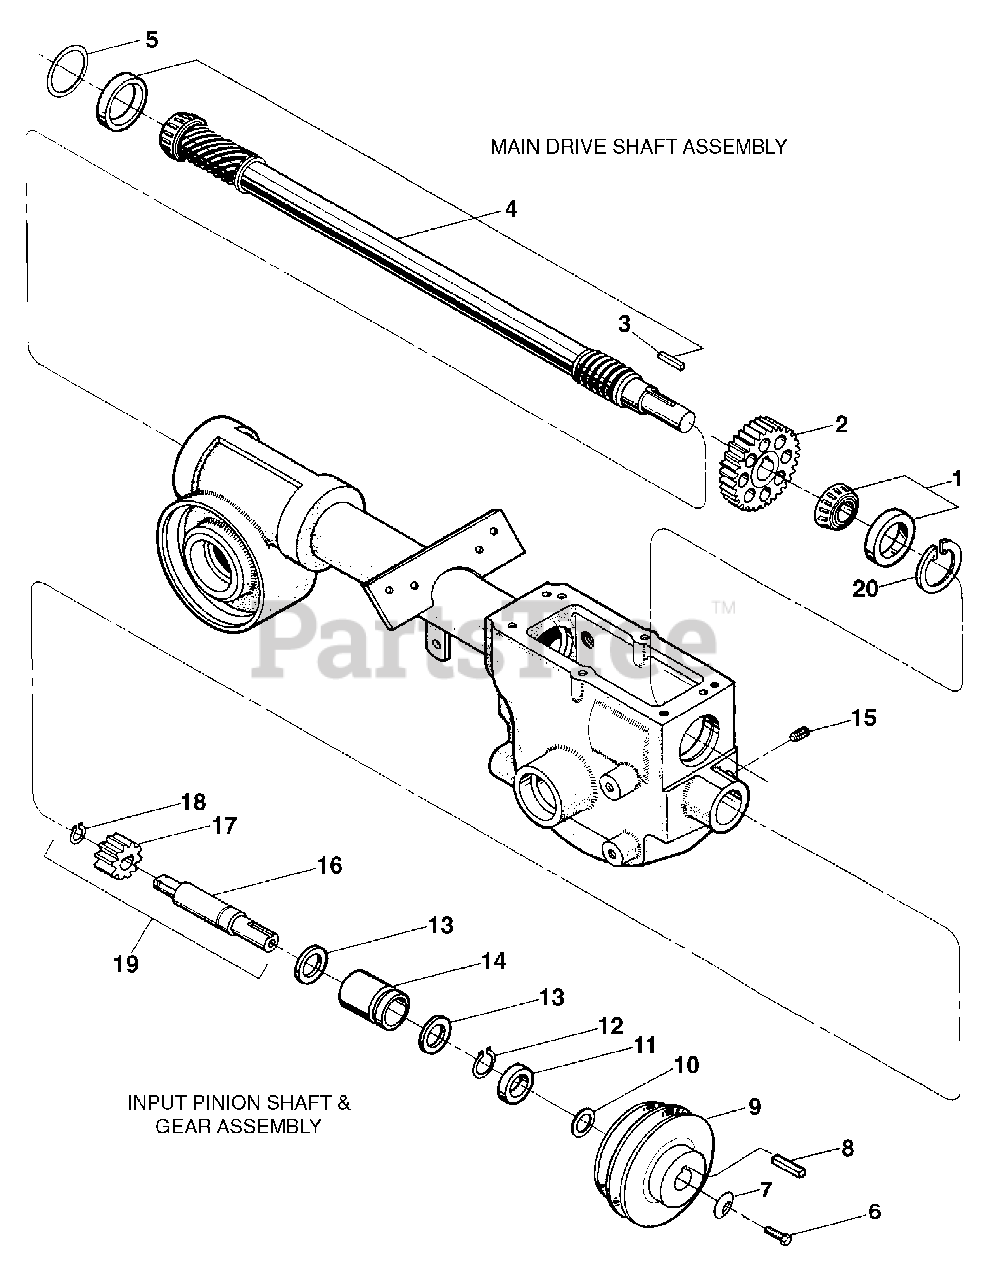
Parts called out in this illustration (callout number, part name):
1	Bearing, Tapered Roller with Race
2	Spur Gear
3	Key, 3/16 sq x 1
4	Main Drive Shaft
5	Shim, Rear Bearing Cap, .010"
5	Shim, same as above, but .030" thick
5	Shim, same as above, but .005 thick
5	Shim Set (Incl. two 1224-2 and one GW-1224-3)
6	Hex Hd. Screw, 5/16-24 x 1-1/8 (Specify GRADE 5 if ordering part locally)
7	Washer, Disc Spring (concave surface faces pulley)
8	Key, 3/16 sq x 1-1/2
9	Transmission Drive Pulley
10	Support Washer
11	Oil Seal, Input Pinion Shaft
12	Retaining Ring (external)
13	Thrust Washer
15	Set Screw, 5/16-18 x 3/8 (Specify GRADE 5 if ordering part locally)
16	Input Pinion (steel shaft)
17	Input Pinion Gear
18	Retaining Ring (external)
19	Pinion Assy. (Incl. One each refs. 16, 17 & 18)
20	Retaining Ring (internal)
